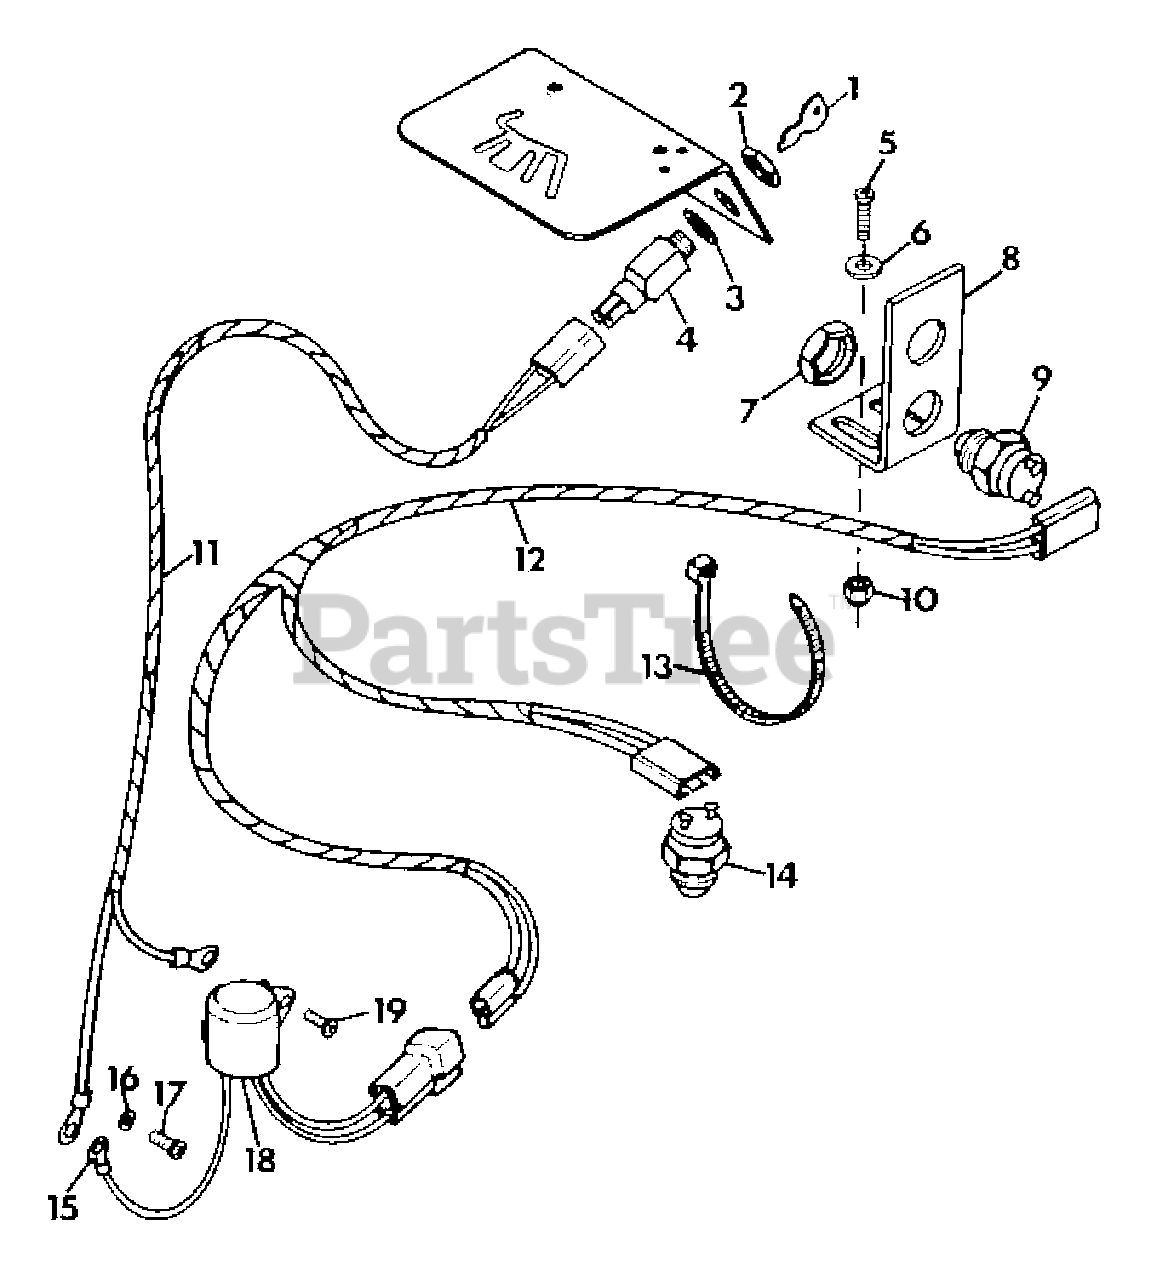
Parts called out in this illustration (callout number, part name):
1	Key, Ignition Switch
2	Nut, Jam 5/8-32
3	Washer, Lock 5/8 Int. Tooth
4	Switch
5	Screw, Machine 10-24x.75 PHD
6	Washer, Flat .188x.438x.049
7	Nut, Stamped 9/16-18
8	Bracket, Interlock Switch
9	Switch, Interlock
10	Nut, Lock 10-24
11	Harness, Wiring Switch
12	Harness, Wiring Interlock
13	Tie, Cable
14	Switch, Neutral Start
15	Terminal, Connector Clip Type
16	Washer, Lock No. 10
17	Screw, Machine 10-32x.50 PHD
18	Control Module
19	Screw, Tapping 10-24x.50 HHD SF
